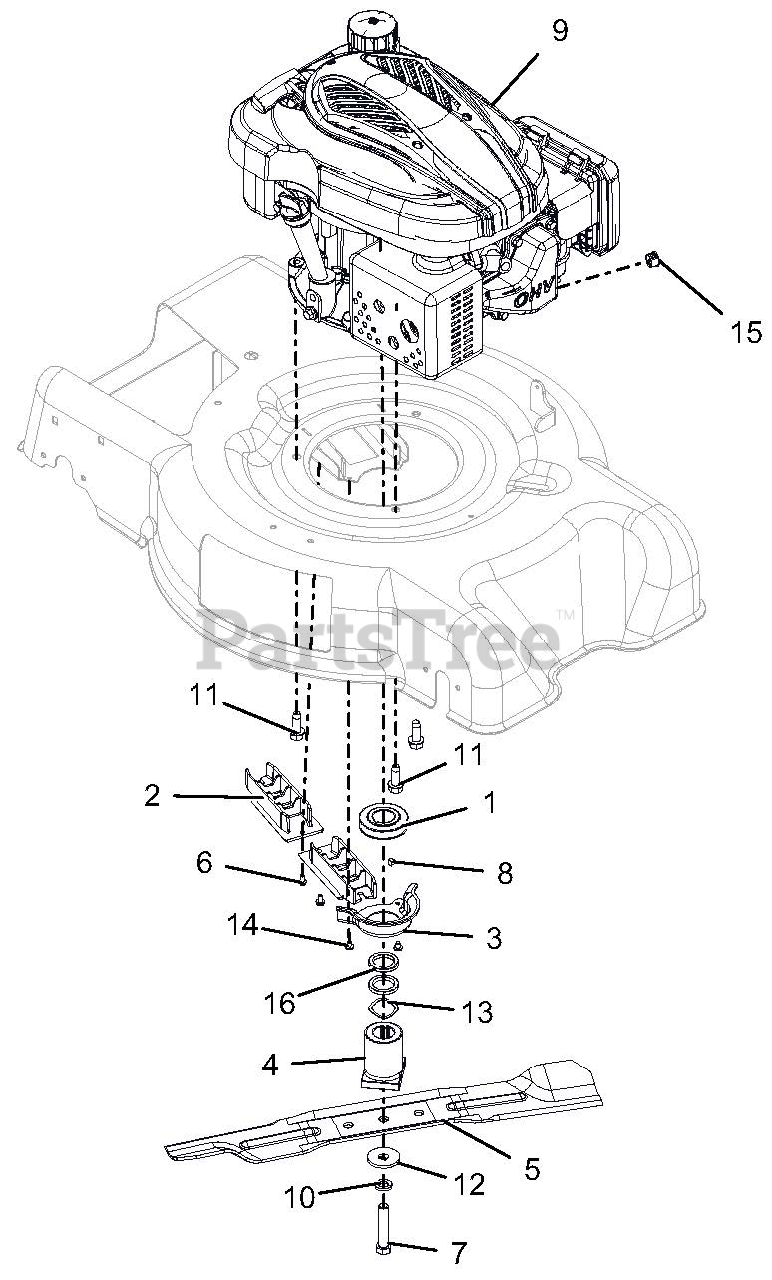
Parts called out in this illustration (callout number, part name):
1	PULLEY,MACHINED POWDER METAL
2	GUIDE, BELT INNER
3	GUIDE, BELT CRANK
4	ADAPTER, BLADE
5	BLADE, MOWER 21" HIGH LIFT
6	SCR-TAP 10-24X.375 PRE-COAT 80
7	@BLT-HEX .4375-20X2.25 GR8 YWZ
8	KEY-SQ .188X.188X.250
9	ENGINE, LONCIN 159CC VERT. ES
10	@WSHR-LK .44X.109 REG YWZC
11	@SCR-TAP .38-16X1.00 HWH TR YZ
12	WSHR-FL-STL .4375X1.50X.125 YZ
13	WASHER - WAVE 1.09X1.37X.016
14	SCR-TAP 10-24X.25 CRSLPH TR YZ
15	PLUG, DOME-BLACK, .625 DIA
16	SPCR, 1.00 X 1.375 X .179
